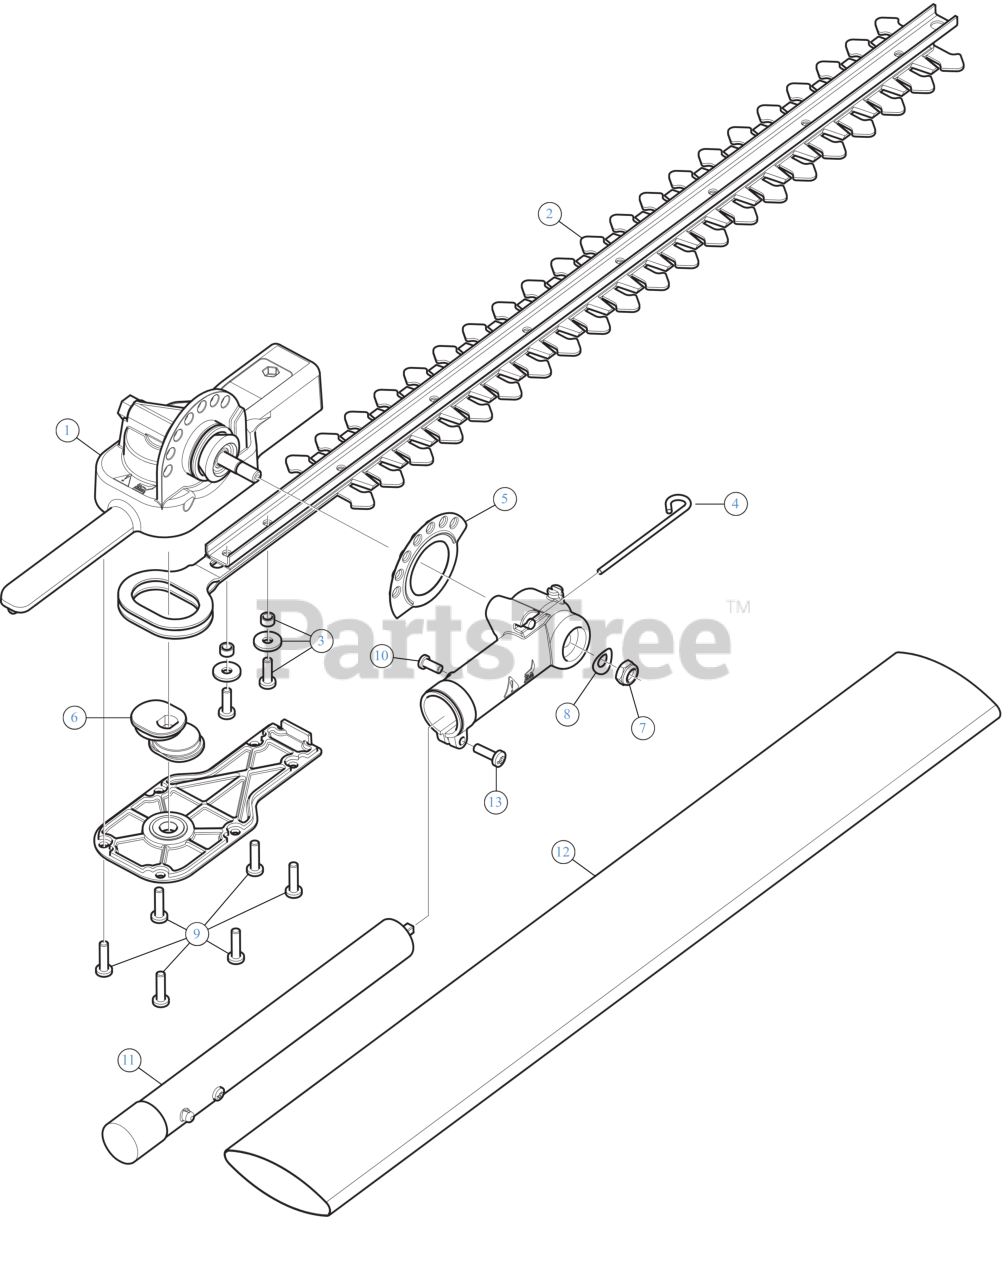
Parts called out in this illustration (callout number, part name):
1	GEARBOX
2	BLADE ASSEMBLY
3	BLADE HARDWARE
4	LOCKING LEVER PIN
5	SPACER DETENT SHM
7	NUT 5/16-24
8	SHAKE PROOF WASHER
9	SCREW - 10-24X.625 PAN HEAD
10	SCREW 8-32X.437
11	BOOM ASSEMBLY
12	BLADE COVER
13	SCR, M5 x 15.8MM
